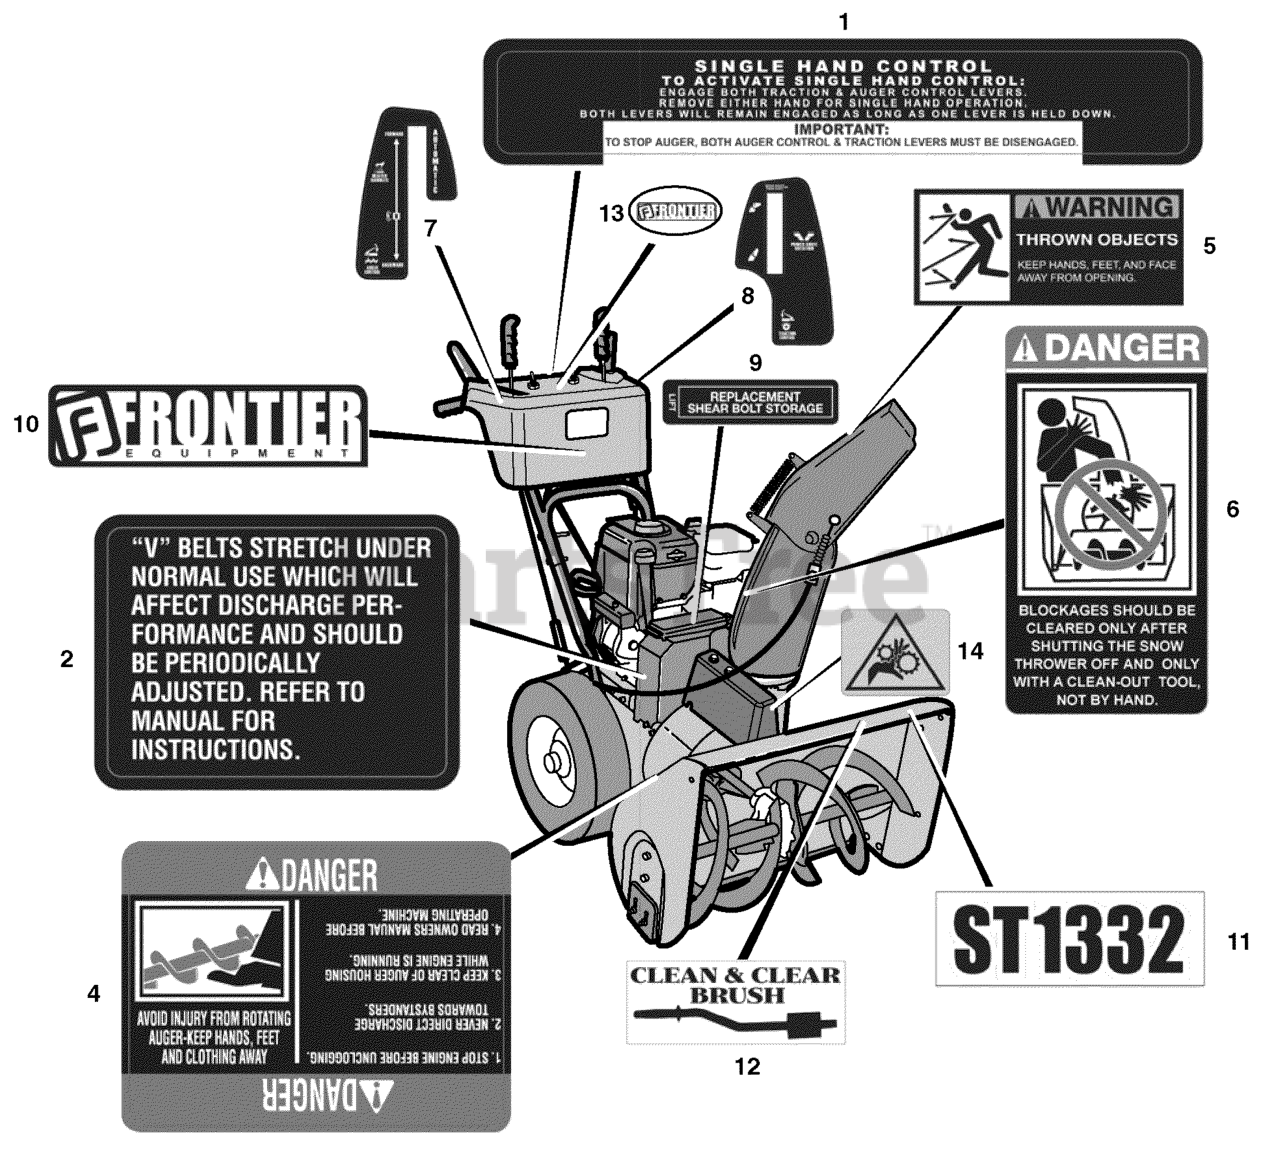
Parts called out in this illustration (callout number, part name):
1	DECAL, SINGLE HAND CONTROL
2	DECAL, V--BELTS
4	DECAL, ROTATING AUGER
5	DECAL, THROWN OBJECT
6	DECAL, UNCLOGGING CHUTE
7	DECAL, SPEED CONTROL
8	DECAL, REMOTE CHUTE CONTROL
9	DECAL, SHEAR BOLTS
10	LOGO NAMEPLATE, FRONTIER
11	DECAL, ST1332
12	DECAL, CLEAN & CLEAR BRUSH
13	DECAL, FRONTIER --CIRCLE
14	DECAL, PINCH POINT -- ELECTRIC CHUTE
